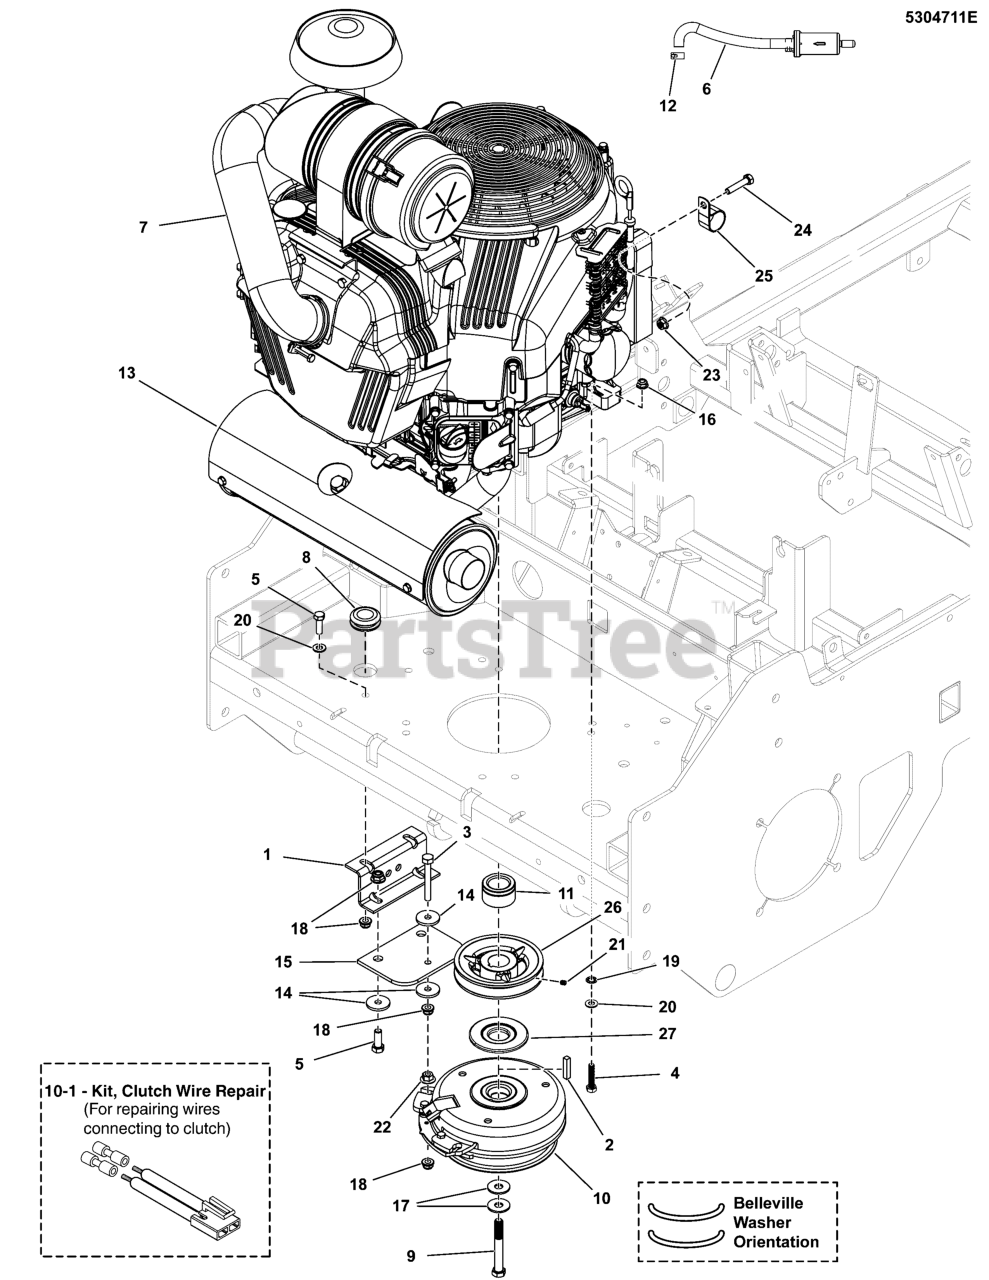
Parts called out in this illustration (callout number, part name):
1	ANCHOR, CLUTCH - BLK
2	KEY, 1/4 SQ X 1-1/4
3	BOLT, 5/16-18 X 2-1/2 GD5 TFL, CZ
4	BOLT, 5/16-24 X 1-3/4, GD8, PHOS
5	BOLT, 5/16-18 X 1 GD5 CZ
6	HOSE/FILTER ASSY
8	GROMMET, 7/8"ID, 1/4" THICK STK
9	BOLT, CRANKSHAFT, 7/16-20 X 3-1/4, GD 8
10	CLUTCH, 250 FT-LBS, WATER GUARD
10-1	KIT, CLUTCH WIRE REPAIR
11	SPACER, 1.13 X 1.75 X 1.35, CZ
12	CLAMP, HOSE, EXTERNAL, 9/16
14	WASHER, .34 X 1.25 X 10 GA
15	CLUTCH ANCHOR PAD
16	NUT, 5/16-24, TOP LOCK FLANGE, GD8 PHOS
17	BELLEVILLE WASHER 1.1875 X .442 X .089
18	NUT, 5/16-18 HEX NYLOCK FLANGE
19	WASHER, 5/16 INT. TOOTH LOCK
20	WASHER, 5/16" SAE
21	SET SCREW. 5/16-18 X 3/8, KNURL, W/PATCH
22	NUT, 5/16-18 HEX SERRATED FLANGE (LARGE)
23	NUT, 5/16-18 HEX SERRATED FLANGE (SMALL)
24	BOLT, 5/16-18 X 1-3/4 GD5 CZ
25	CLAMP, VINYL INSULATED, 1.00
26	PULLEY, 4.75 OD X 1-1/8 BORE, BC-48
27	WATER GUARD, WARNER C 250 FT-LBS CLUTCH
